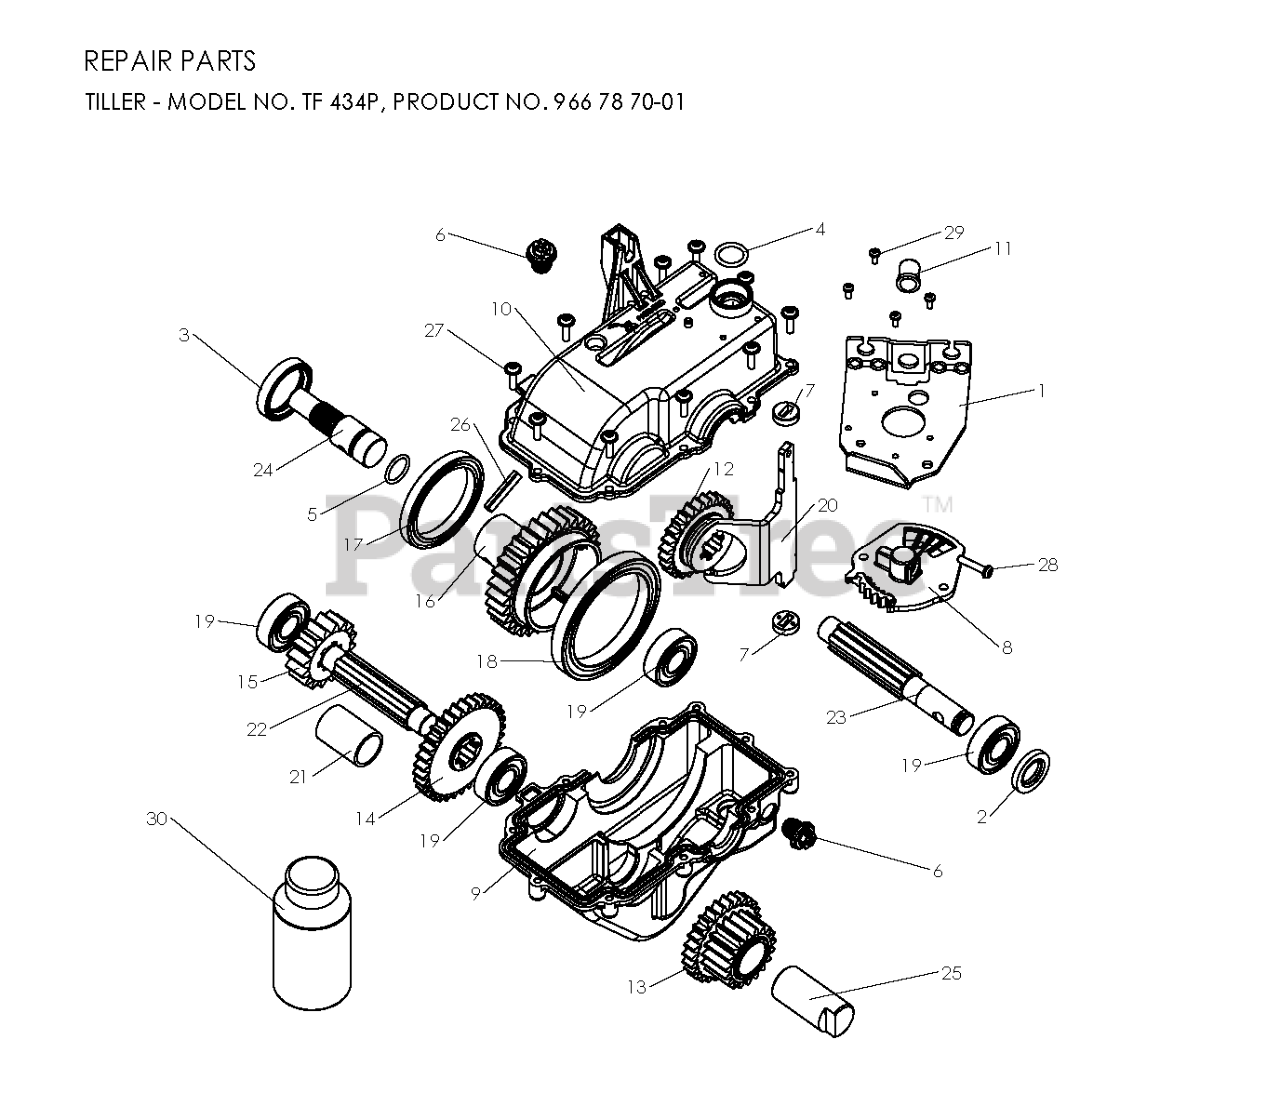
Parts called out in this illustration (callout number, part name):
11	SPRING BALL
17	BALL BEARING 6810
18	BALL BEARING 6813
19	BALL BEARING
